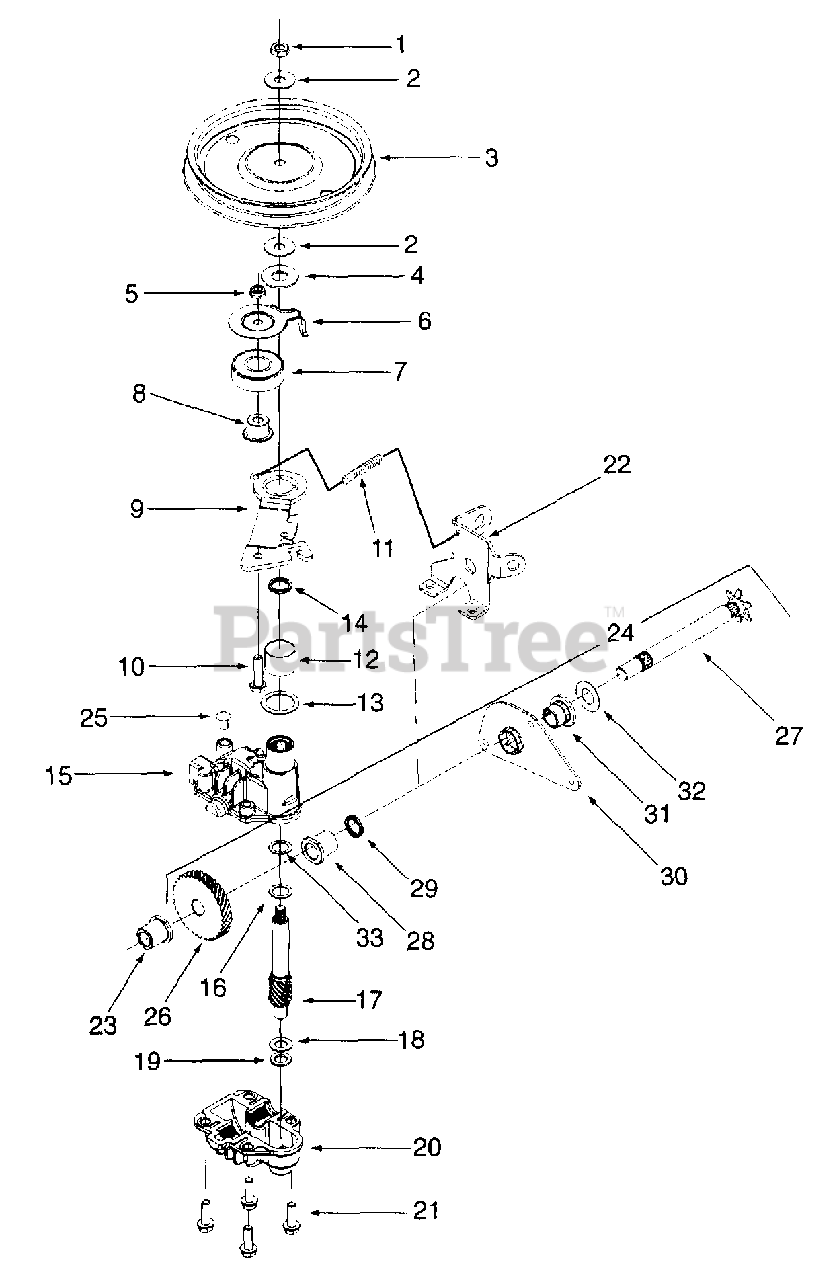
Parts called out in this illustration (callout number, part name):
1	Hx. Jam Nut 5/16-24
2	Bell Wash. .325 x .930 x .045
3	Pulley
4	Fl. Wash. .510 x 1.120 x .060
5	Hx. Jam Nut 1/4-28
6	Belt Keeper
7	Bearing
8	Flange Spacer
9	Idler Bracket Assembly
10	Hx. Cap Scr. 1/4-28 x 1.00 Gr. 5
11	Extension Spring
12	Bearing Sleeve
13	Fl. Wash. .885 x 1.145 x .030
14	Oil Seal
15	Upper Housing Assembly
16	Thrust Wash. .504 x .700 x .030
17	Pinion Shaft 10 T.
18	Thr. Wash. 3/8 x .70 x .030
19	Thr. Wash. .388 x .625 x .062
20	Lower Housing Assembly
21	Hx. Scr. 1/2-20 x .75
24	Shaft Assembly
26	Gear 34 T.
27	Output Shaft 6 T.
28	Flange Bearing
29	Oil Seal
30	Pivot Bracket
31	Flange Bearing
32	Wash. Fl. .508 I.D. x 1.00 O.D. x .020
33	Bearing
